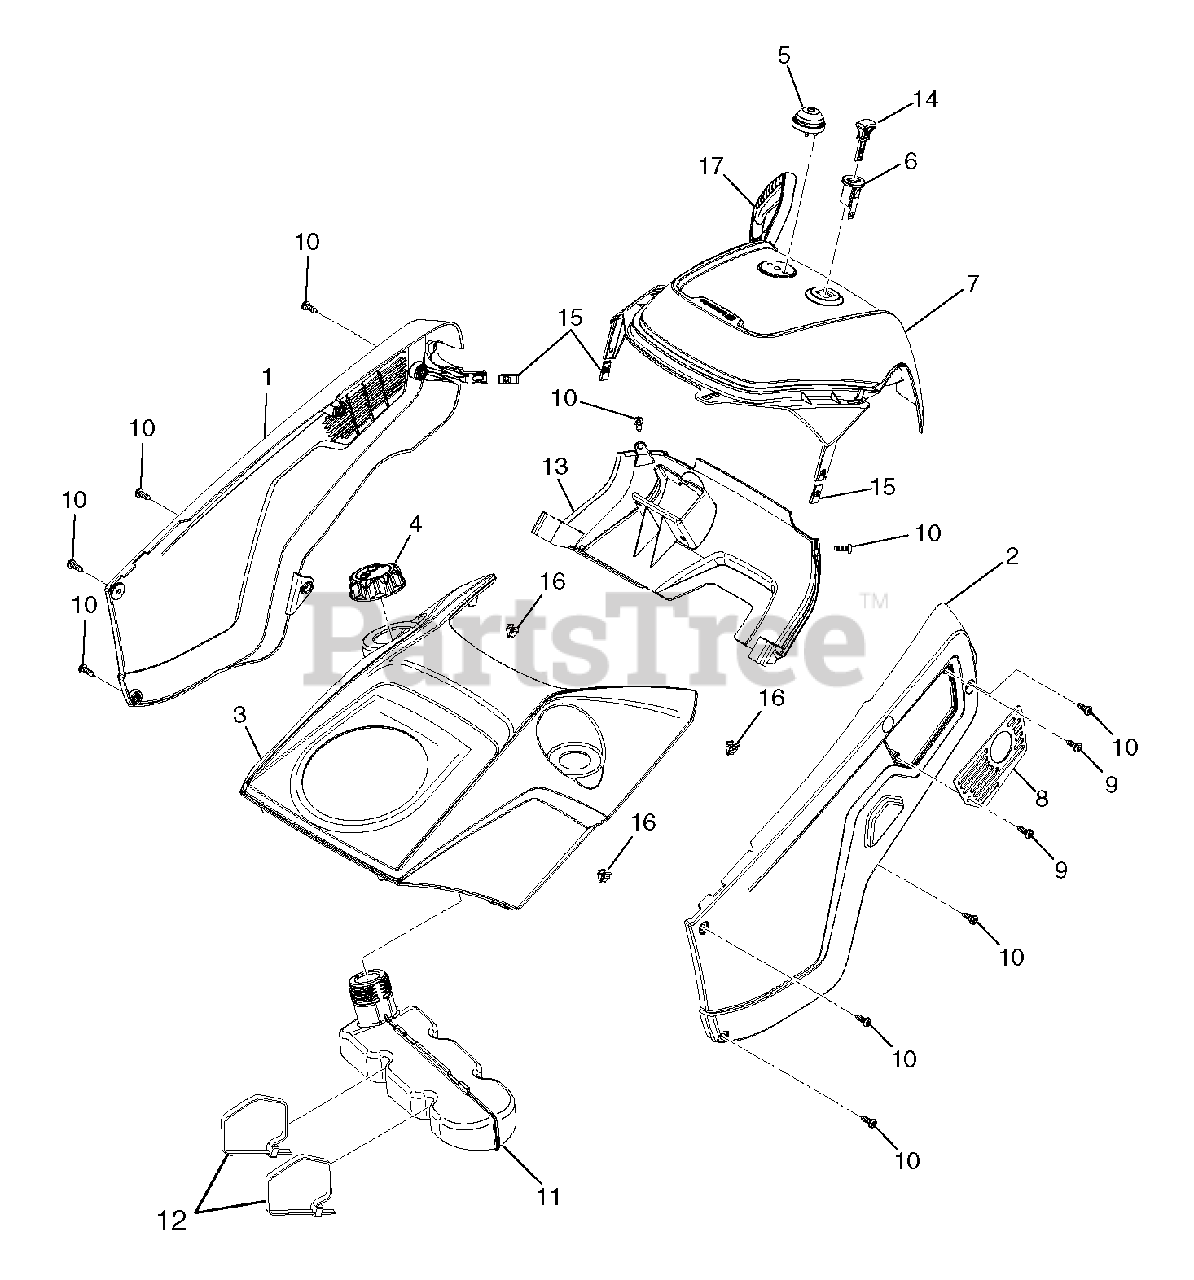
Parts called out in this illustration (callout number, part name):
1	COVER.NON-DRIVE.SIDE.HUSQ.GRAY
2	COVER.DRIVE.SIDE HUSQVARNA.SNO
3	COVER.TOP.SSST.ORANGE
4	CAP ASM.FUEL.2.25"FR.
5	RP BULB.PRIMER
6	KEY HOUSING
7	COVER.REAR.UPPER.GREY
8	PLATE.EXHAUST.PNT.
9	SCREW.HX.13X.750
10	SCREW.PAN.HD.TORX.1/4-20X.750
11	TANK.FUEL.ASM
12	TIE.CABLE.24.5X.29.NYLON.WHITE
13	COVER.REAR.LOWER.SSST.HUSQ.GRE
14	KEY.SINGLE.STAGE.HUSQVARNA
17	HANDLE.STARTER.SNOW
